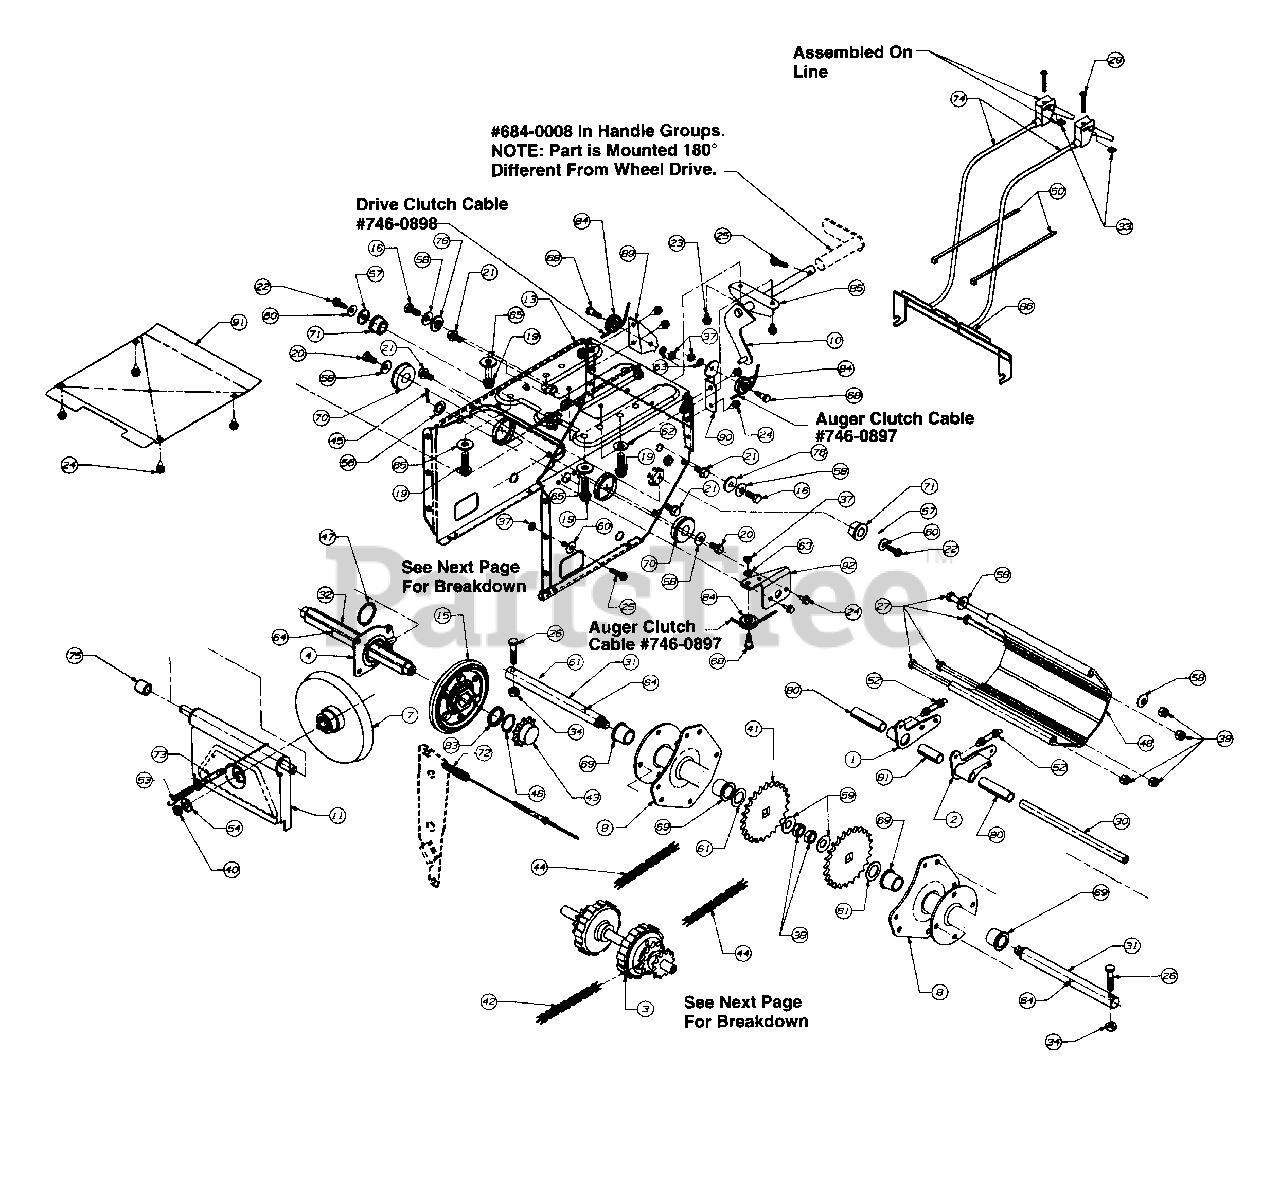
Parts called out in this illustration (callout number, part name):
1	Dog Assembly, R.H.
2	Dog Assembly, L.H.
3	Drive Shaft Assembly
4	Bearing Friction Wheel
7	Friction Wheel Disc
10	Rod Shift, Track Drive
15	Wheel Friction
16	Hex Cap Screw
18	Hex Screw
19	Hex Self-Tap Screw
20	Hex Self-Tap Screw
21	Screw, Hex
22	Screw, Hex
23	Screw, Hex
24	Hex, Screw
25	Screw, Hex
26	Screw, Hex
27	Screw, Hex
29	Scr., Oval
30	Shaft
31	Axle, Drive
33	Nut, Flange
34	Nut, Hex Lock
37	Nut, Hex Jam
38	Hex Ins. Jam
39	Hex L-Nut
40	Jam Nut, Hex
41	Sprocket
42	Chain, Endless
43	Drive Sprocket
44	Chain, Endless
45	Pin, Cotter
46	Ring, Snap
47	Ring, Retainer
48	Housing, Track
50	Cable Tie
52	Spring
53	Extension Spring
54	Washer
56	Washer, Flat
57	Washer, Flat
58	Washer, Bell
59	Washer, Bell
60	Washer, Bell
61	Washer, Flat
62	Washer, Flat
63	Washer, Lock
64	Washer, Flat
65	Washer, Flat
68	Shoulder Screw
69	Bearing, Flange
70	Bearing, Ball, With Snap Ring
71	Bearing, Flange
72	Cable, Auger
73	Cable, Clutch
74	Cable, Track Steer w/Trigger
75	Spacer
76	Shoulder Spacer
80	Spacer, Split
81	Spacer, Split
83	Spacer
84	Roller, Cable
